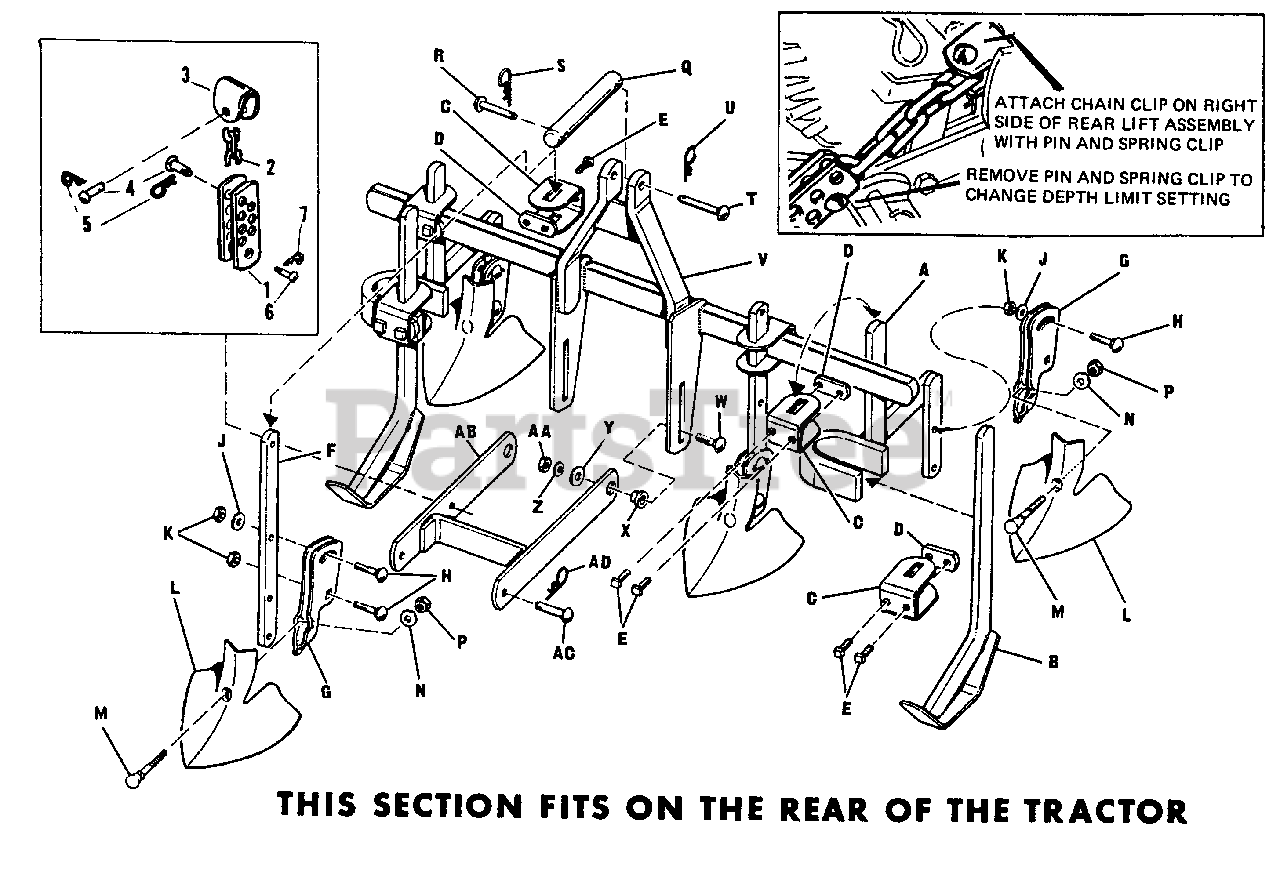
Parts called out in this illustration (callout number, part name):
1	Bracket-Depth Limit
2	Chain
3	Clip-Chain
5	Clip-Hairpin
7	Clip-Hairpin
A	Standard Tool Assembly
B	Shoe Weld Assembly
C	Clamp Shank, 3/16" x 2" x 8"
D	Special Nut, 5/16" x 1" x 2-1/2"
E	Set Screw, 3/8"-16 x 1"
F	Standard Tool, 7/16" x 1-1/4" x 14-1/8"
G	Tool Holder Assembly
H	Carriage Bolt, 3/8"-16 x 1-1/4"
J	Plain Washer, 3/8"
K	Full Hex. Nut, 3/8"-16
L	Universal Sweep, 3/16" x 8"
M	Plow Bolt, 7/16"-14 x 2"
N	Plain Washer, 7/16"
P	Full Hex. Nut, 7/16"-14
Q	Attaching Rod
R	Pin, 3/8" x 2"
S	Spring Clip
T	Pin, 3/8" x 2-3/8"
U	Spring Clip
V	Rear Tool Bar Assembly
W	Carriage Bolt, 7/16"-14 x 1-1/2"
Y	Washer, 3/8"
Z	Lock Washer, 7/16"
AA	Full Hex. Nut, 7/16"-14
AB	Arm Assembly
AC	Rd. Hd. Pin, 7/16" x 1-3/4"
AD	Clip Spring
